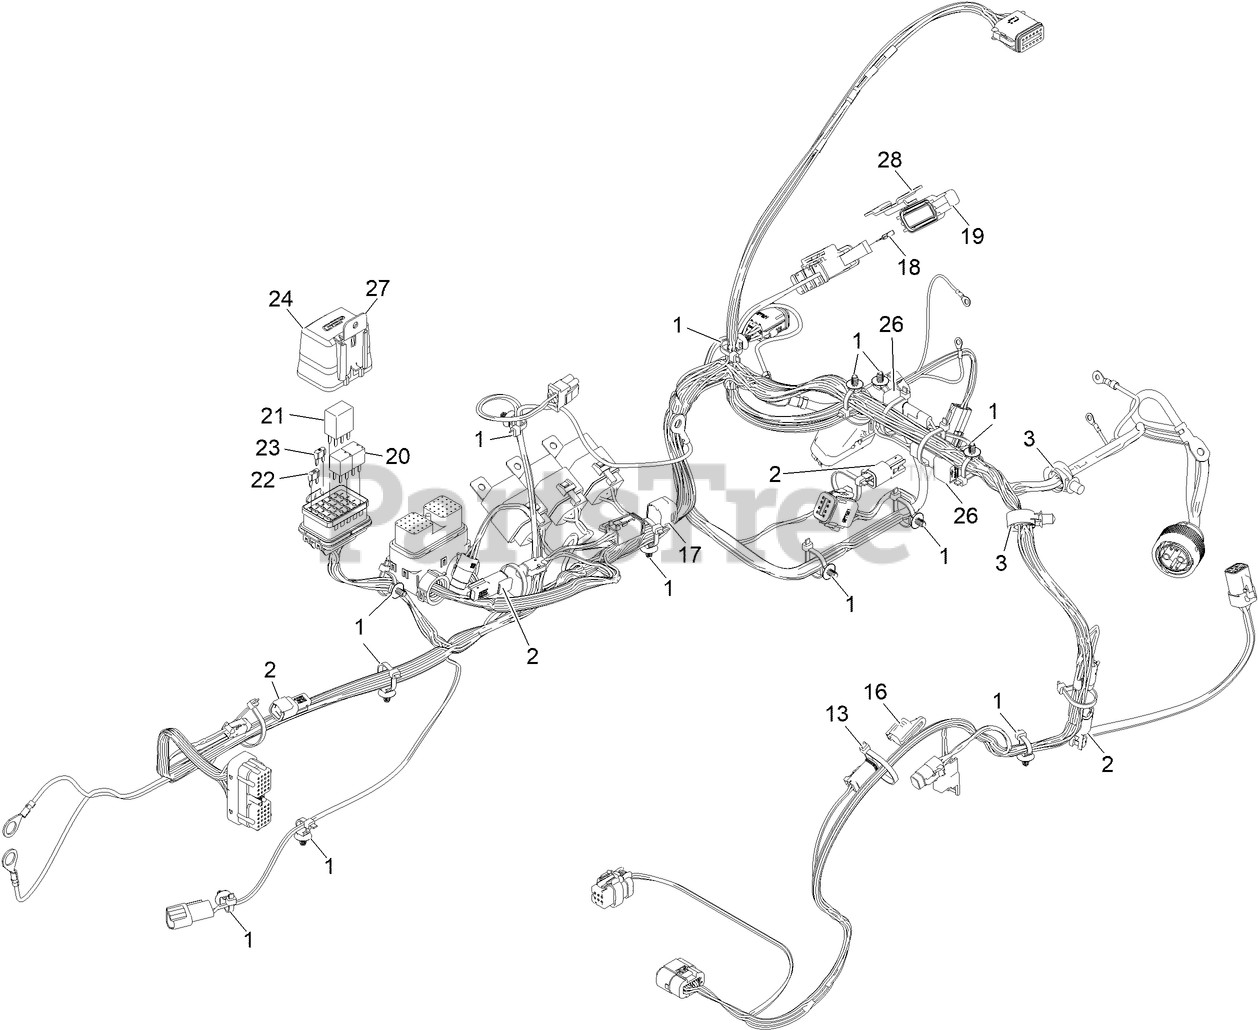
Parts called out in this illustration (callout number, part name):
1	CLIP-TIE, FIR TREE W/TIE, 5MM/.196"" HOLE
2	RESISTOR-120 OHM
3	CLIP-TIE
13	TIE-CABLE
16	Cover-2 Pin Connecor
17	CAP-PLUG, 6 WAY
18	Fuse-Mini Blade, 10 Amp
19	Cover-Littelfuse, Pdm 6W
20	RELAY-MICRO
21	RELAY-MICRO 280, SPDT
22	FUSE-MINI BLADE, 20 AMP
23	FUSE-MINI BLADE, 15 AMP
24	Cover-Fuseblock, 24F, Gep
27	CLIP-MOUNTING
28	Bracket-Littelfuse.Pdm
